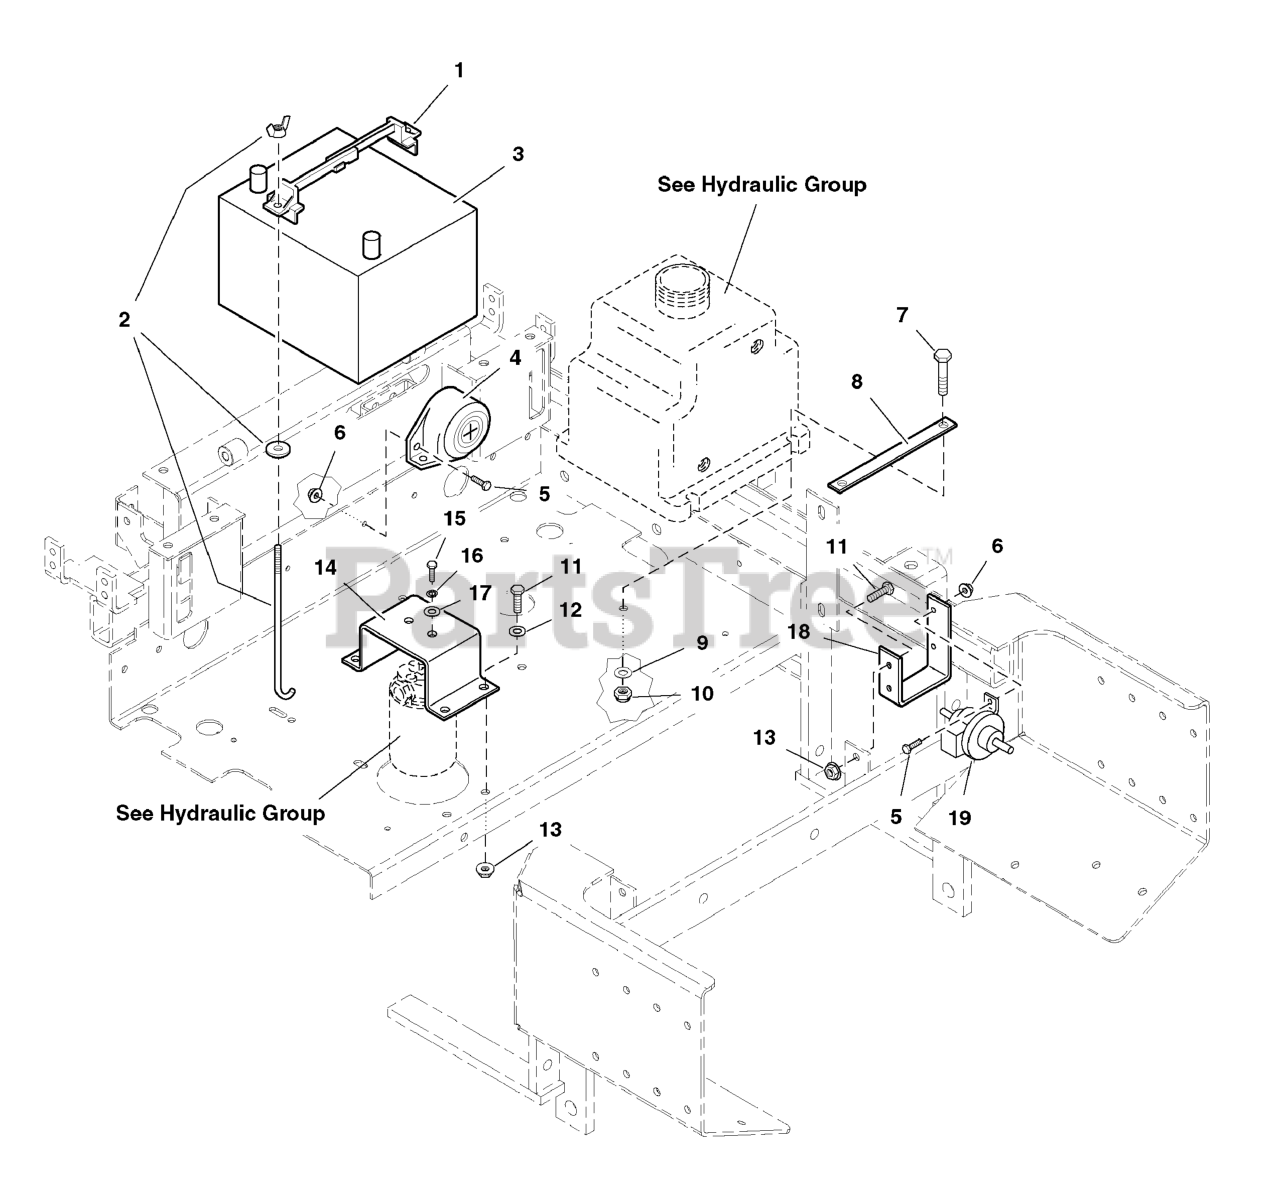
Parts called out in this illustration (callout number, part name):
1	BATTERY HOLDDOWN
2	BATTERY HOLDDOWN BOLT
3	BATTERY, Lawn & Garden, 12V (BCIU1, 340 CCA)
5	BOLT, 1/4-20 X 1" GD5 CZ
6	NUT, 1/4-20 HEX SERR. FLANGE
7	BOLT, 3/8-16 X 2-1/4" GD5 CZ
8	HOLD DOWN PLATE
9	WASHER, 3/8 SAE
10	NUT, 3/8-16 HEX NYLON LOCK
11	BOLT, 5/16-18 X 3/4 GD5
12	WASHER, 5/16" SAE
13	NUT, 5/16-18 HEX SERRATED FLANGE (SMALL)
14	MOUNT, Oil Filter
15	BOLT, 1/4-20 x 3/4
16	WASHER, 1/4 LOCK
17	WASHER, 1/4 SAE
18	FUEL PUMP MOUNT
19	FUEL PUMP
